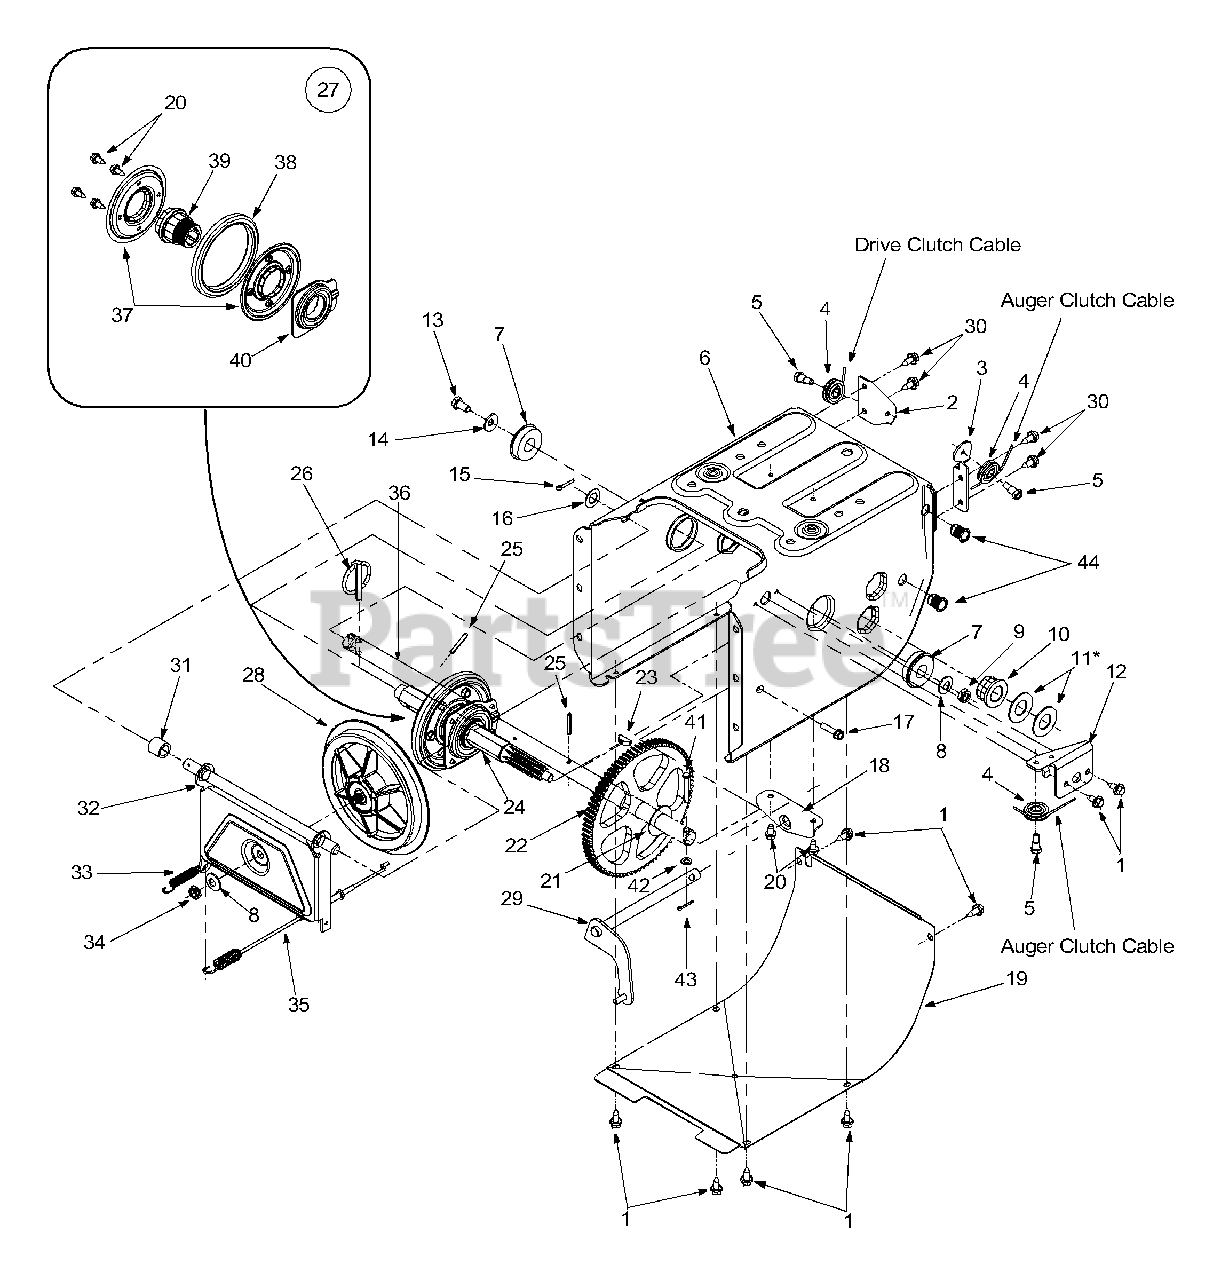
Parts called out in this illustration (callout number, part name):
1	Self-tapping Screw, 1/4-20 x .625
5	Hex Screw 1/4-28
6	Frame Assembly
7	Ball Bearing
8	Bell Washer
9	Lock Jam Nut
10	Hex Flange Bearing
11	Flat Washer
14	Bell Washer .340 ID x .872 OD
15	Cotter Pin
16	Flat Washer .536 ID x .930 OD
17	Self-tapping Screw, 1/4-20 x 1.25
21	Flat Washer .760 ID x .50 OD
24	7-Tooth Shaft
25	Roll Pin
26	Klik Pin
27	Friction Wheel Assembly
28	Friction Disc Wheel
29	Wheel Shift Rod Assembly
30	Self-tapping Screw, 1/4-20 x .5
31	Spacer
34	Jam Nut 3/8-24
35	Drive Cable
36	Axle 13" Wheels
37	Friction Plate
38	Friction Wheel Rubber
39	Friction Wheel Hub
40	Friction Wheel Bearing
41	Clevis Pin, 1/4 x 1.3725
42	Flat Washer, .281 x .5 x .063
43	Cotter Pin, .75
44	Insert Nut, 5/16-18
